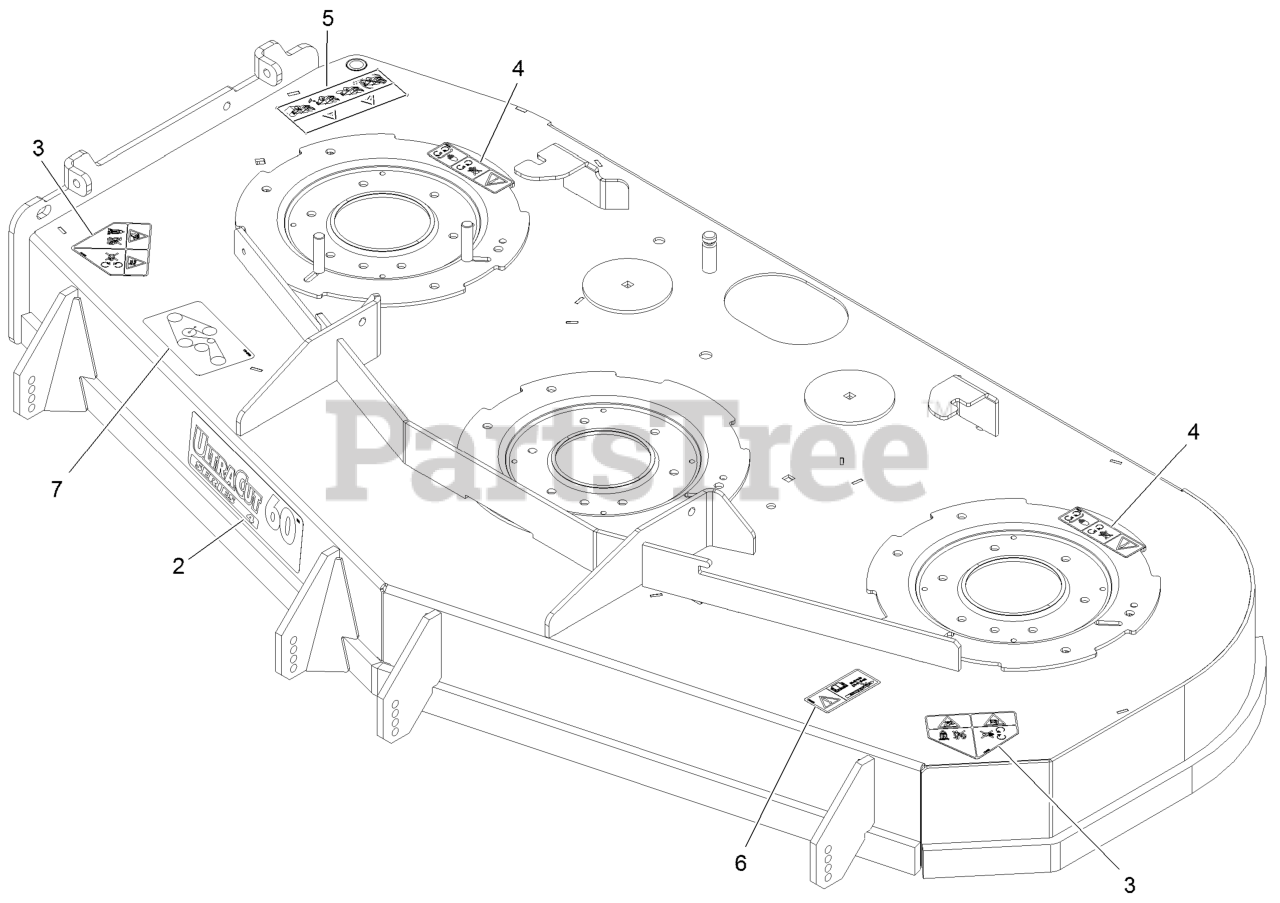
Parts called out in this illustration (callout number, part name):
2	DECAL,ULTRACUT 60 SERIES
3	DECAL-DANGER
4	DECAL-WARNING, BAGGER
5	DECAL-BOLT TORQUE
6	DECAL-COVER, MISSING
7	DECAL-BELT ROUTING
